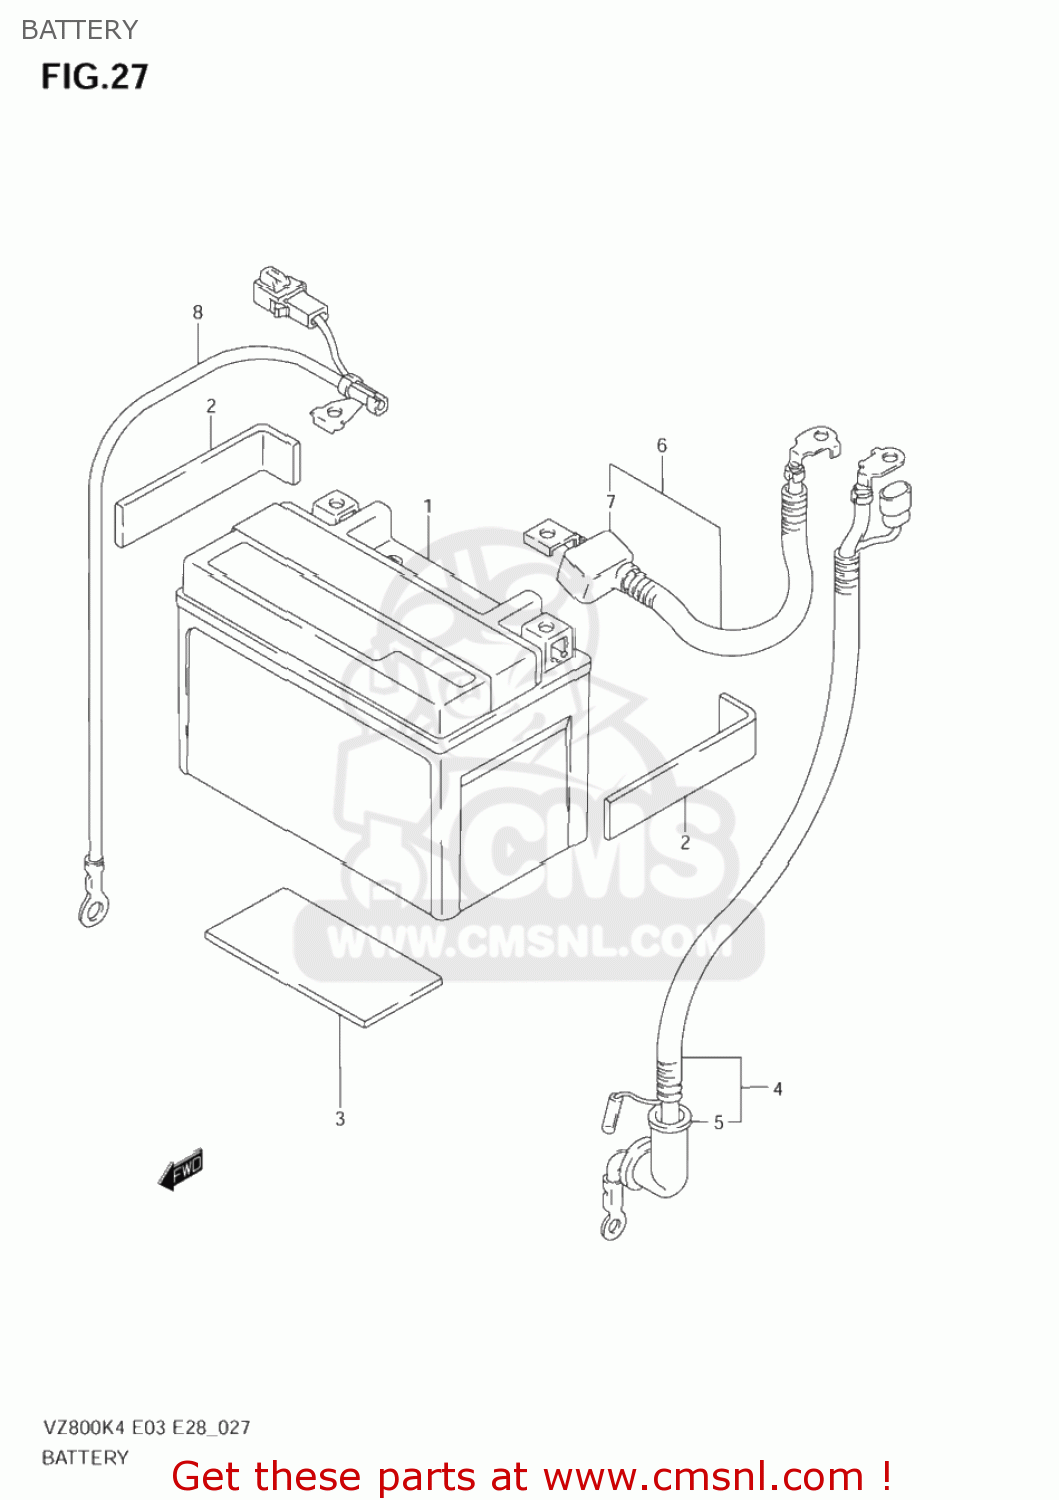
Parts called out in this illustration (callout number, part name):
1	BATTERY ASSEMBLY (12V) FTX
2	PROTECTOR(170X95X3.0)
3	PROTECTOR(170X95X3.0)
4	WIRE,STARTER MOTOR LEAD
5	CAP,STARTER MOTOR LEAD
6	WIRE,BATTERY PLUS LEAD
7	CAP,BATTERY PLUS
8	WIRE,BATTERY MINUS
